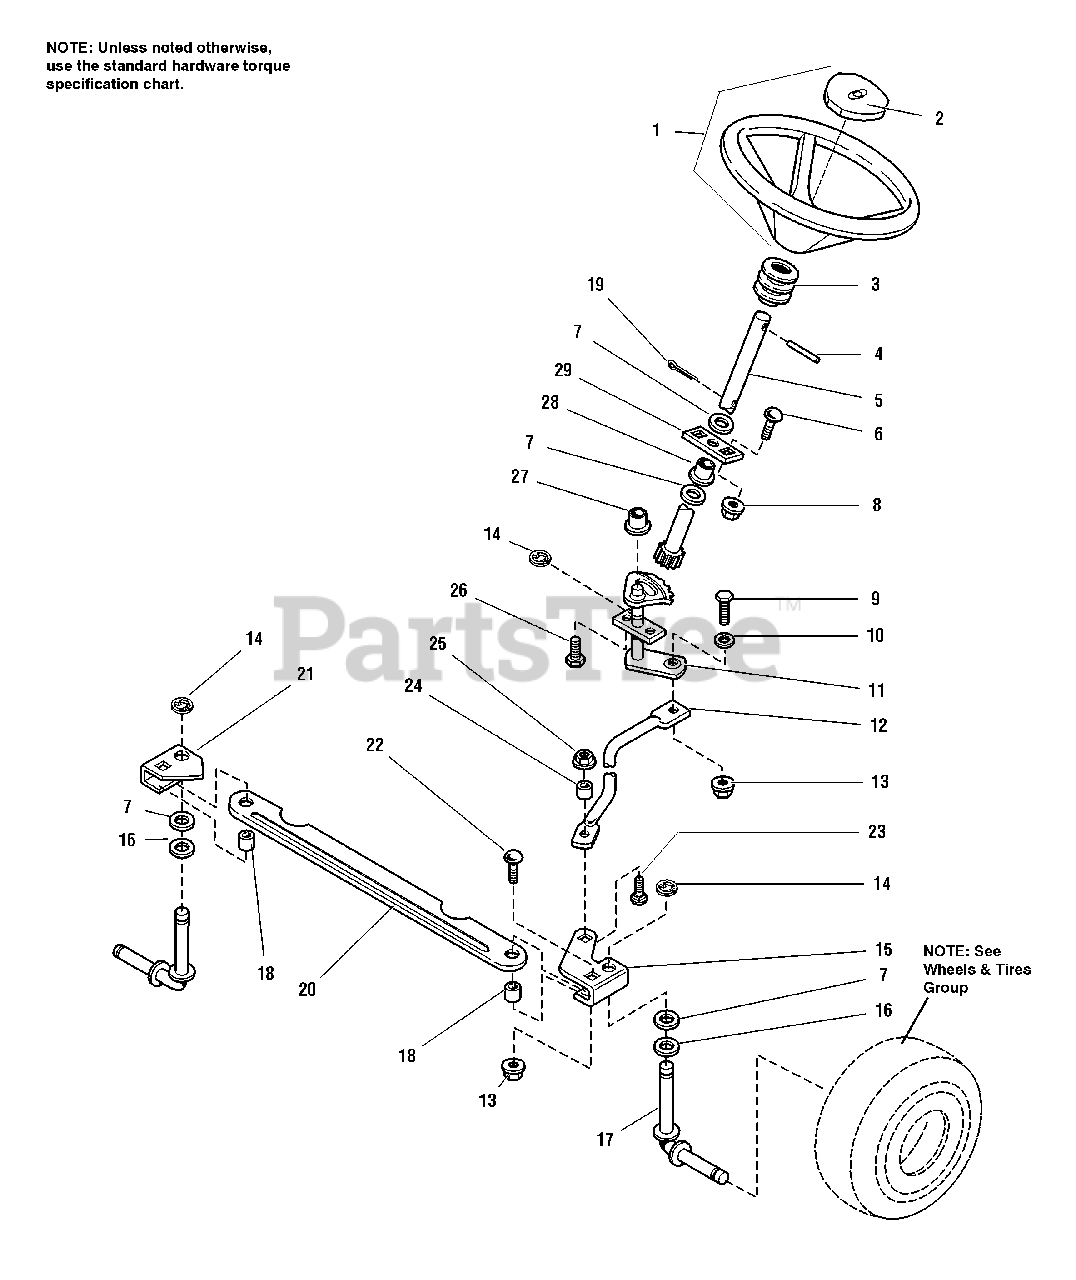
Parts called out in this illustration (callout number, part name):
1	STEERING WHEEL ASSEMBLY
2	CAP, Steering Wheel
4	PIN, Spring, 5/16 x 2-1/2
5	SHAFT ASSEMBLY, Steering
6	CARRIAGE BOLT, 3/8-16 x 1
7	WASHER, 3/4
8	NUT, Hex Flange Whiz Lock, 3/8-16
9	CAPSCREW, Hex Hd, 3/8-16 x 1-1/4
10	WASHER, 3/8
11	STEERING GEAR ASSEMBLY
13	NUT, Hex Flange Whiz Lock, 3/8-16
15	ARM, Steering, LH
16	WASHER, 3/4
17	SPINDLE ASSEMBLY
19	PIN, Cotter, 3/16 x 1-1/4
21	ARM, Steering, RH
22	CARRIAGE BOLT, 3/8-16 x 1-1/4
23	CARRIAGE BOLT, 5/16-18 x 1
25	NUT, Hex Flange Lock, 5/16-18
26	CAPSCREW, Taptite Hex Washer Hd, 5/16-18 x 3/4
29	PLATE, Steering, Mounting
